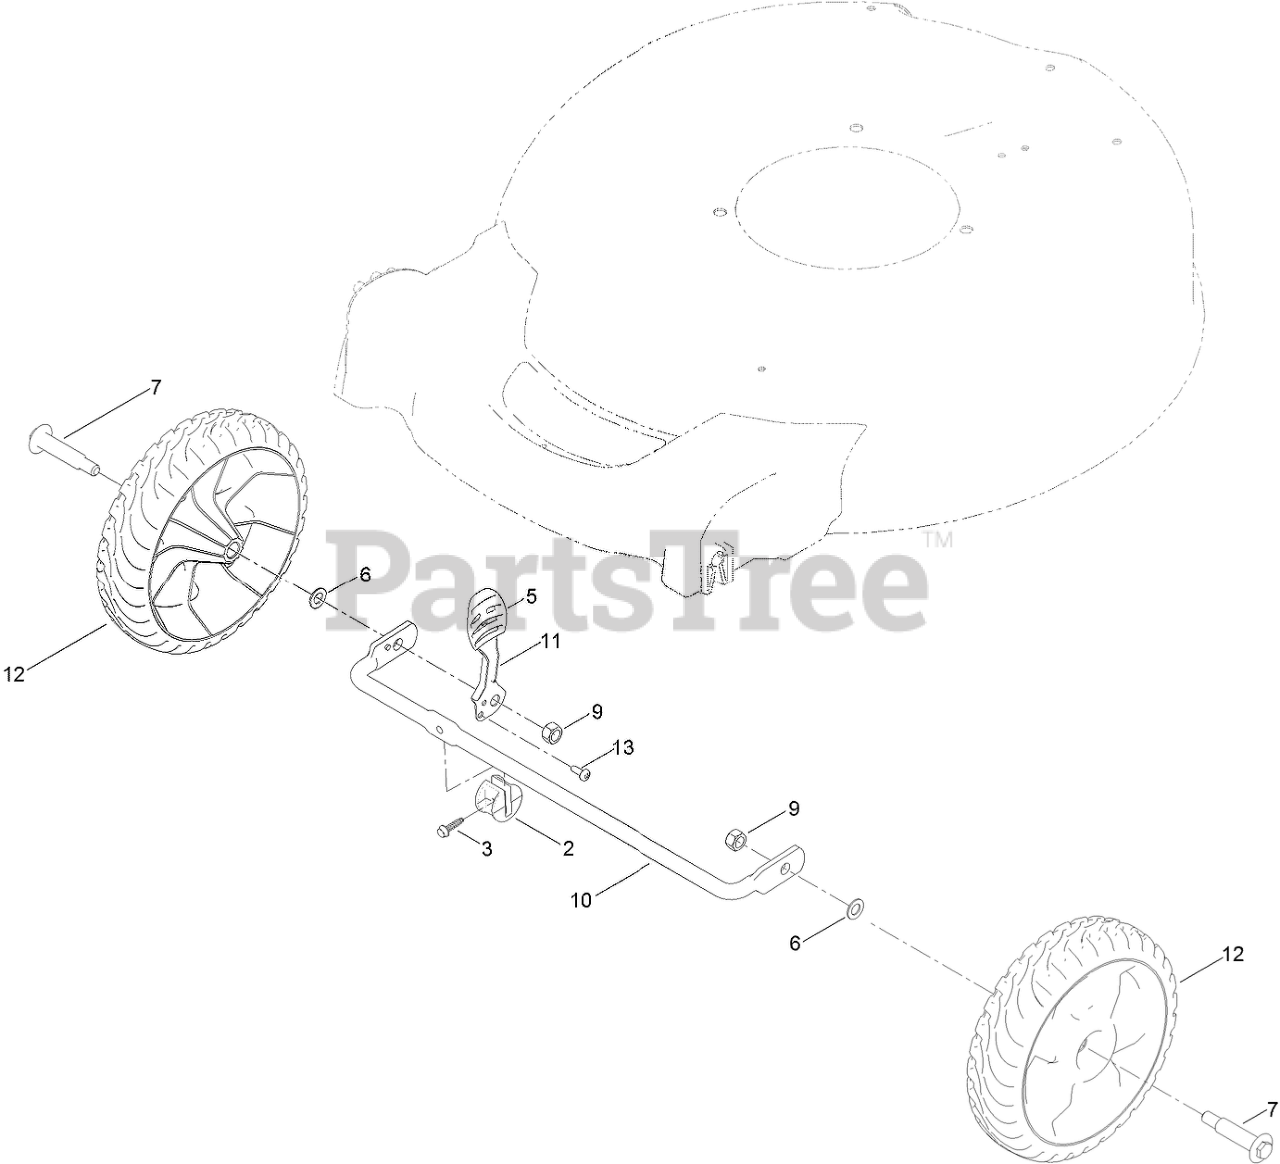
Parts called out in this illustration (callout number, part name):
2	STOP-AXLE
3	SCREW-HWH
5	Knob-Lever, HOC
6	WASHER
7	BOLT-SHOULDER
9	NUT-HEX
10	AXLE-FRONT
11	ARM-SPRING
12	8 INCH WHEEL ASM
13	SCREW-FORMING, THREAD
